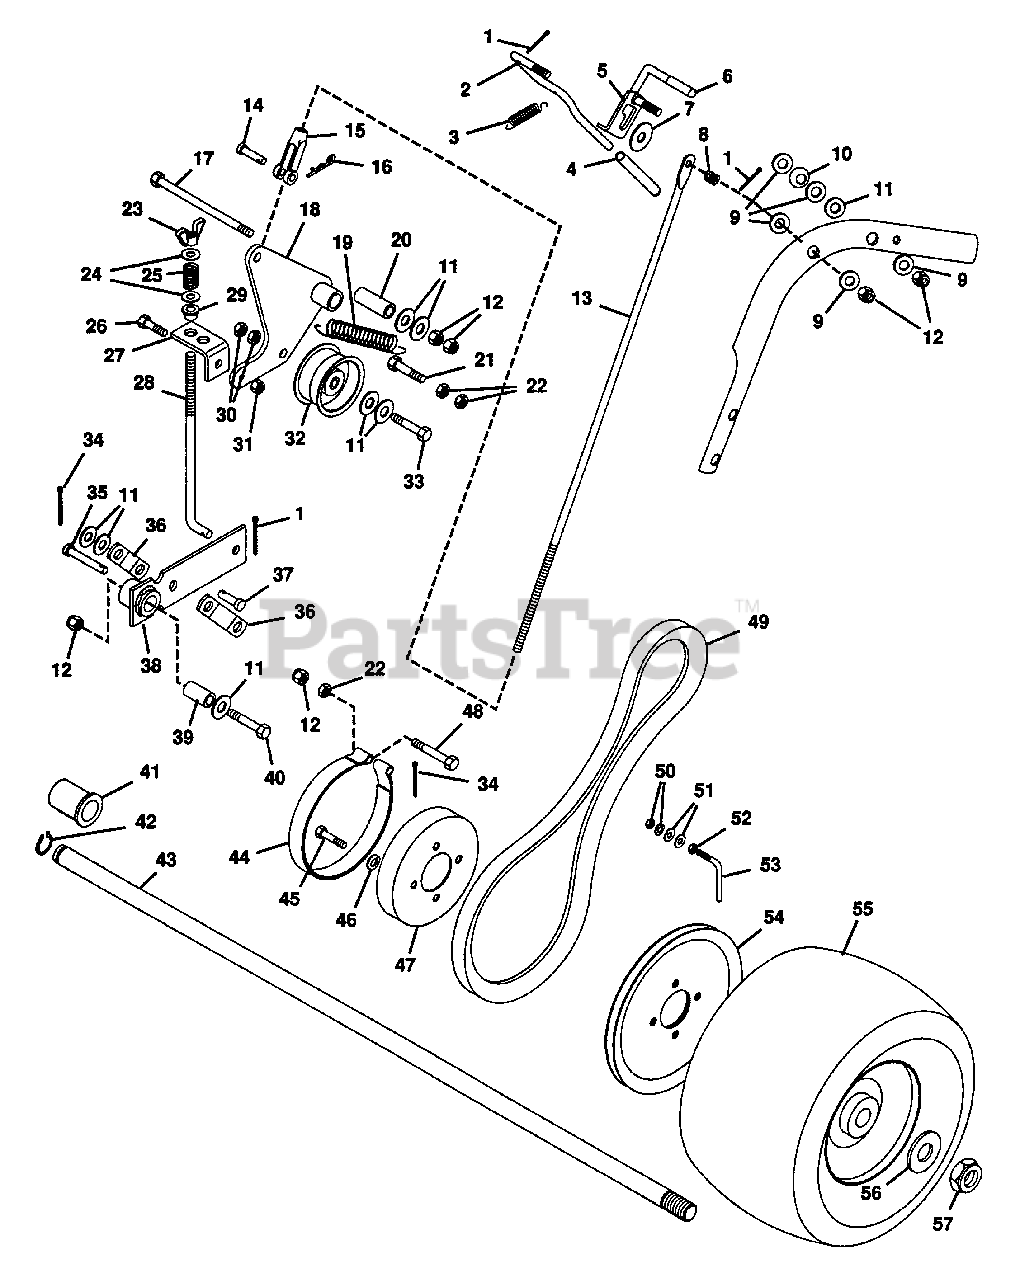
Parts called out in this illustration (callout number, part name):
1	PIN, COTTER .09X.75
2	LEVER, HAND CONTROL
3	SPRING, EXTENSION
4	GRIP, HAND CLUTCH LEVER
5	WELDMENT, CLUTCH-BRAKE LOCK
6	TIP, BRAKE LOCK LEVER
7	WASHER, FLAT .438X1.375X.083
8	SPRING, COMPRESSION
9	WASHER, NYLON .375X.75X.06
10	WASHER, SPRING .375 I.D.
11	WASHER, FLAT .406X.812X.065
12	NUT, LOCK 3/8-16
13	ROD, CLUTCH ACTUATING
14	PIN, CLEVIS .375X.948
15	CLEVIS, 3/8-24 ADJUSTABLE
16	PIN, COTTER HAIR
17	BOLT, HEX 3/8-16X3.25
18	WELDMENT, WHEEL CLUTCH ARM
19	BUSH., ST. .385X.610X1.80 STL.
20	SPRING
21	BOLT, HEX 3/8-16X1.50
22	NUT, HEX 3/8-16
23	NUT, WING 5/16-18
24	WASHER, FLAT .344X.688X.065
25	SPRING, COMP. 1X.78X338 LB/IN
26	BOLT, HEX 1/4-20X.750
27	BRACKET, BRAKE ROD
28	ROD, BRAKE
29	BUSH., FLG. .320X.620X.312 NY.
30	NUT, LOCK 3/8-16
31	NUT, LOCK 1/4-20
32	PULLEY, IDLER
33	BOLT, HEX 3/8-16X1.875
34	PIN, COTTER .125X.75
35	PIN, CLEVIS 3/8X1.093
36	LINK, BRAKE ARM
37	PIN, CLEVIS 3/8X.594
38	WELDMENT, BRAKE ARM
39	BUSH., ST. .391X.622X.950 STL.
40	BOLT, HEX 3/8-16X1.75
41	BUSH., FLG. 1.00X1.25X1.40 NY.
42	RING, RETAINING
43	SHAFT, AXLE (PRO 32)
44	ASSEMBLY, BRAKE BAND
45	BOLT, HEX 5/16-18X1.00
46	WASHER, LOCK 5/16 REG.
47	DRUM, BRAKE
48	BOLT, HEX 3/8-16X2.00
49	BELT-V, DRIVE WHEEL (PRO 32)
50	NUT, HEX 1/4-20
51	WASHER, FLAT .281X.625X.065
52	WASHER, LOCK 1/4 REG.
53	ROD, PULLEY CLEANING
54	SHEAVE, PRO 32 DRIVE WHEEL
55	ASSEMBLY, WHEEL 13X5.00-6
56	RACE, BEARING THRUST
57	NUT, LOCK 3/4-10 LIGHT THIN
